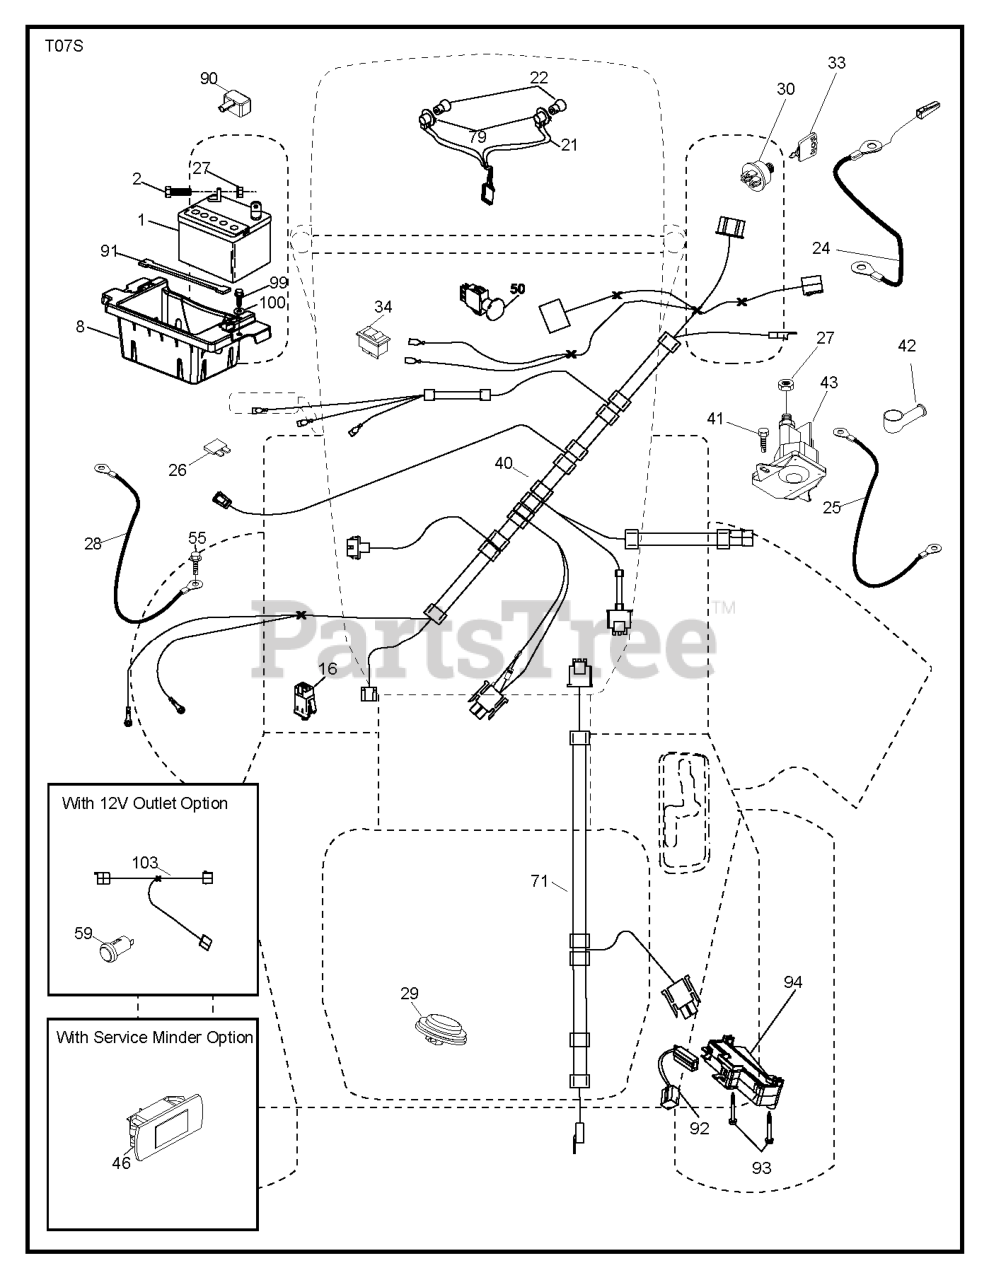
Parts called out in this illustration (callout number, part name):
1	Battery 12 Volt 25 Amp
2	BOLT.HEX.1/4.X.3/4.DICHROMATE
8	TRAY.ASM.BATTERY.FRT.TEX.CARB
16	SWITCH INTERLOOK PUSH-IN
21	HARNESS.LIGHT W/4152J BULBS
24	CABLE.BATT.POS.WIRE.TG.DA SOL
25	CABLE.STARTER.6G.BL/RED.17.5
26	FUSE 20AMP
27	NUT
28	CABLE GROUND 6 GA 21" 90T BLK
29	SWITCH.SEAT.DELTA.OPC.
30	SWITCH.IGN.DELTA.W.LGH.ROS
33	KEY.CHAIN.BLISTER.PACK.GEN.USA
40	HARNESS.IGN.DASH.HUQ/P
41	SCREW
42	TERMINAL COVER
43	SOLENOID.W/BRASS.PLUNGER
46	RP.GUAGE.SRVCMNDR.HRMTR.
50	RP.SWTICH.PTO.8.TERMINAL
55	SCREW 5/16"
59	OUTLET.12-VOLT
71	HARNESS-CHASSIS SUB
79	BULB HOLDER ASM.
90	COVER.TERMINAL.BATTERY
91	STRAP.BATTERY.MOUNT.FRONT(2 2)
92	HARNESS.PIGTAIL.CONSLE
93	SCREW.PLASTITE
94	MODULE.REVERSE.ROS
99	SCREW HEXWSHR 1/4-20X3/4
100	WASHER
103	HARNESS PIGTAIL 12V OUTLET
